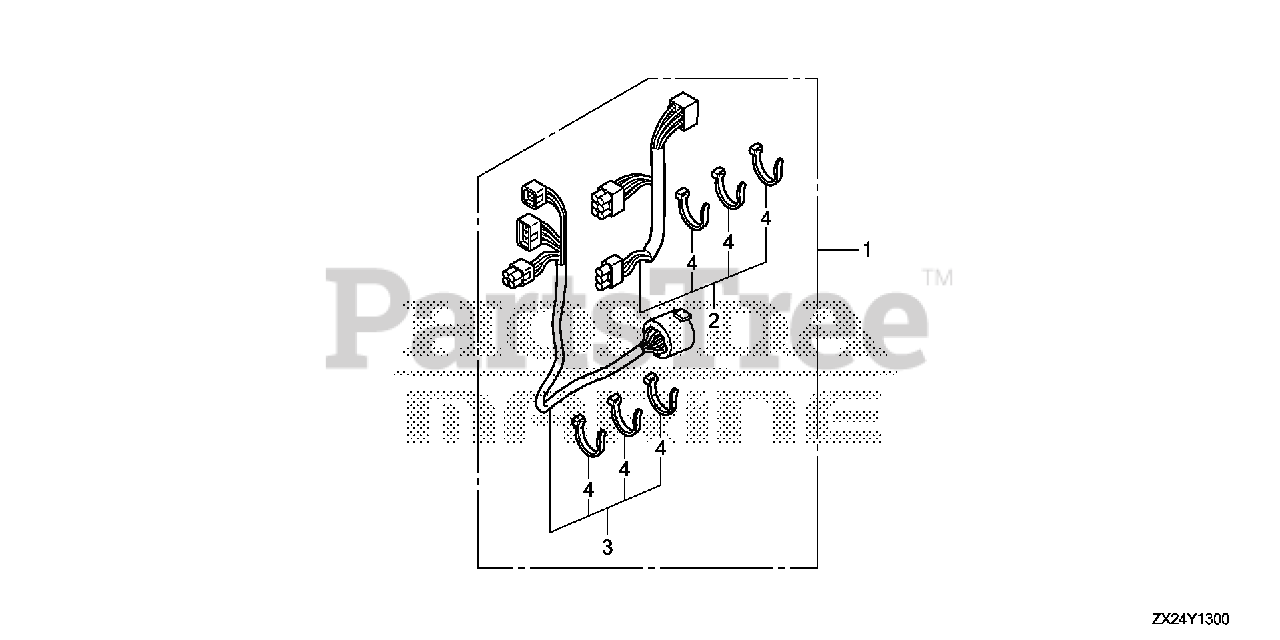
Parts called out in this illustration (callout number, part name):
1	CABLE SET, PANEL INDICATOR (20FT)
1	CABLE SET, PANEL INDICATOR (25FT)
1	CABLE SET, PANEL INDICATOR (30FT)
2	WIRE ASSY., INDICATOR (20FT)
2	WIRE ASSY., INDICATOR (25FT)
2	WIRE ASSY., INDICATOR (30FT)
3	CABLE ASSY., SWITCH PANEL (20FT) (NHK MEC)
3	CABLE ASSY., SWITCH PANEL (25FT) (NHK MEC)
3	CABLE ASSY., SWITCH PANEL (30FT) (NHK MEC)
3	CABLE ASSY., SWITCH PANEL (20FT)
3	CABLE ASSY., SWITCH PANEL (30FT)
